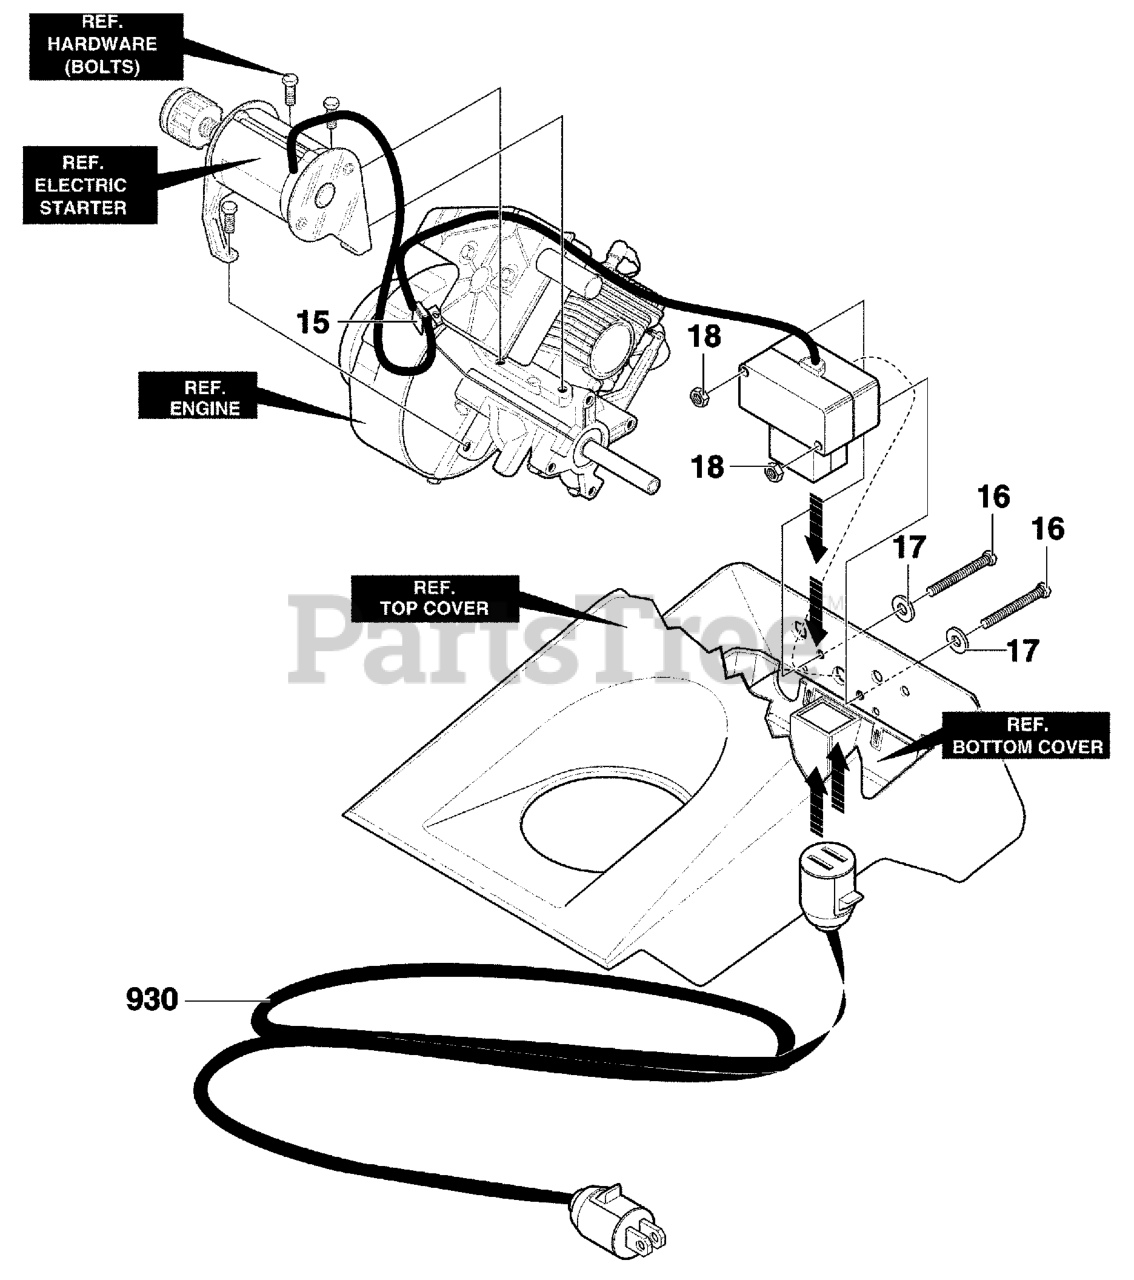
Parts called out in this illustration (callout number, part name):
15	RETAINER
16	SCREW #8-32X3.00
17	WASHER, FLAT .188X.38X.040
18	NUT, #8-32X3.00
930	CORD EXTENSION
